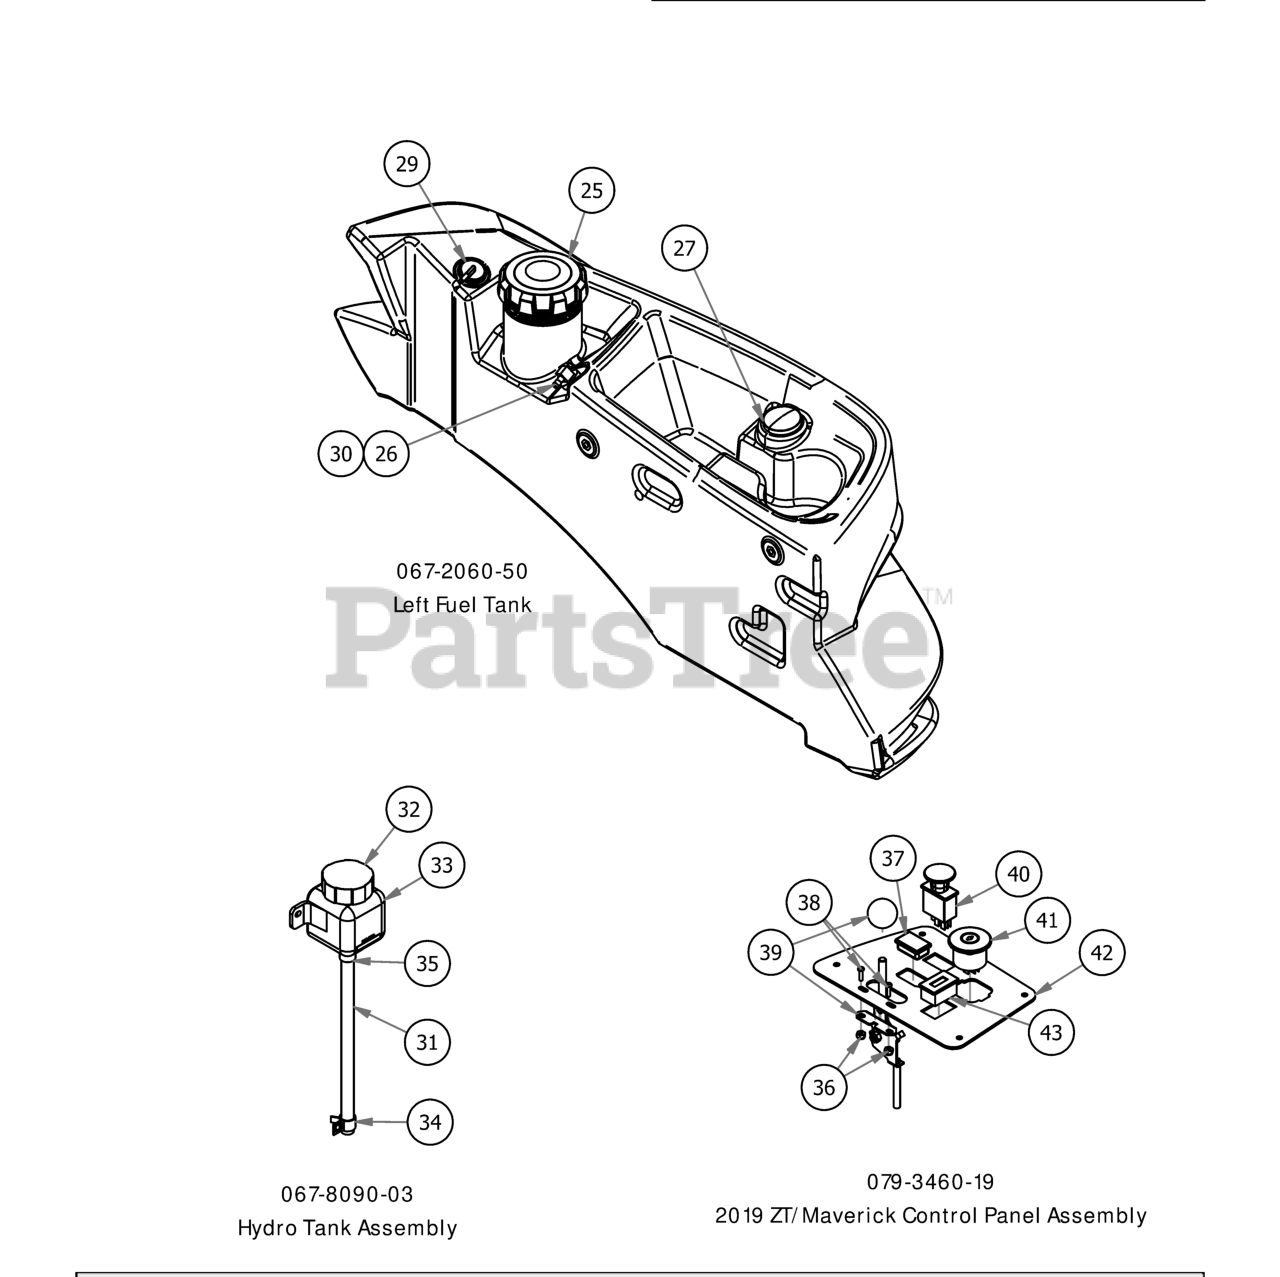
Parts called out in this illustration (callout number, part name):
27	Fuel Gauge w/Grommet
29	Rollover Valve W/Grommet
30	Pick-Up Grommet
31	ZT/Maverick Hydro Tank Hose
32	Hydraulic Tank Cap
33	350ml Expansion Tank
34	3/8" Hose Clamp
35	1/2 Hose Clamp
36	10-24 Nylon Insert Locknut Zinc Orange Nylon
37	Light Plug
38	10-24 X 5/8 BS Button Head Bolt
39	Throttle Lever Assembly
40	PTO Engager
41	Ignition Switch
42	Control Panel
43	Tachometer
